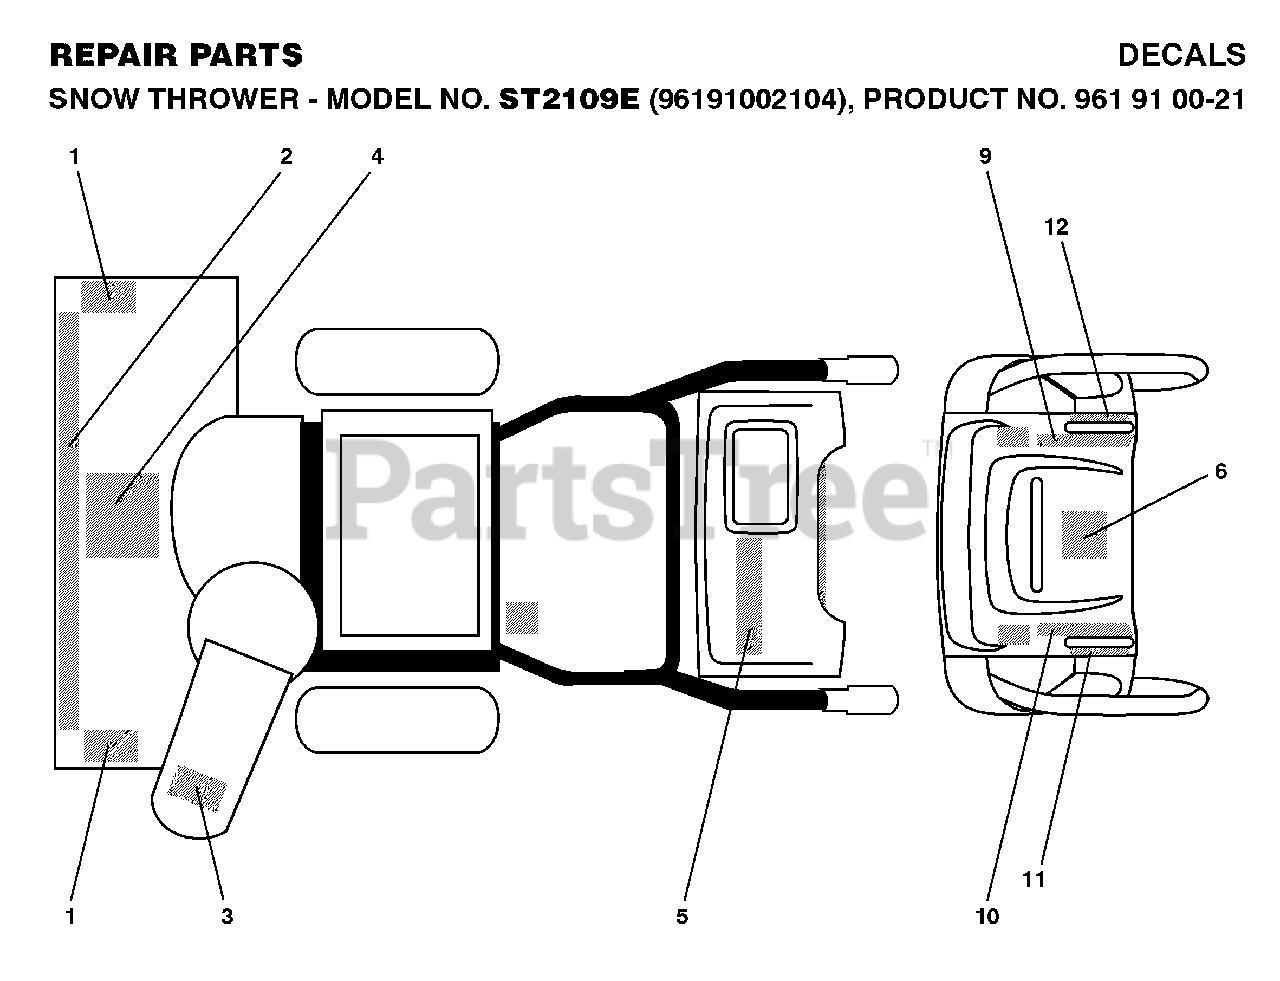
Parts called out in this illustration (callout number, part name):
1	DECAL.AUGER.SAFETY.
3	DECAL.CHUTE.SAFETY.
4	DECAL.AUGER."
6	DECAL.CONSOLE.INSTRUCTION
10	DECAL.REM.DEFLECTOR.LT
11	DECAL.POWER.STEER.LT.TRIG.INT
12	DECAL.POWER.STEER.RT.TRIG.INT
